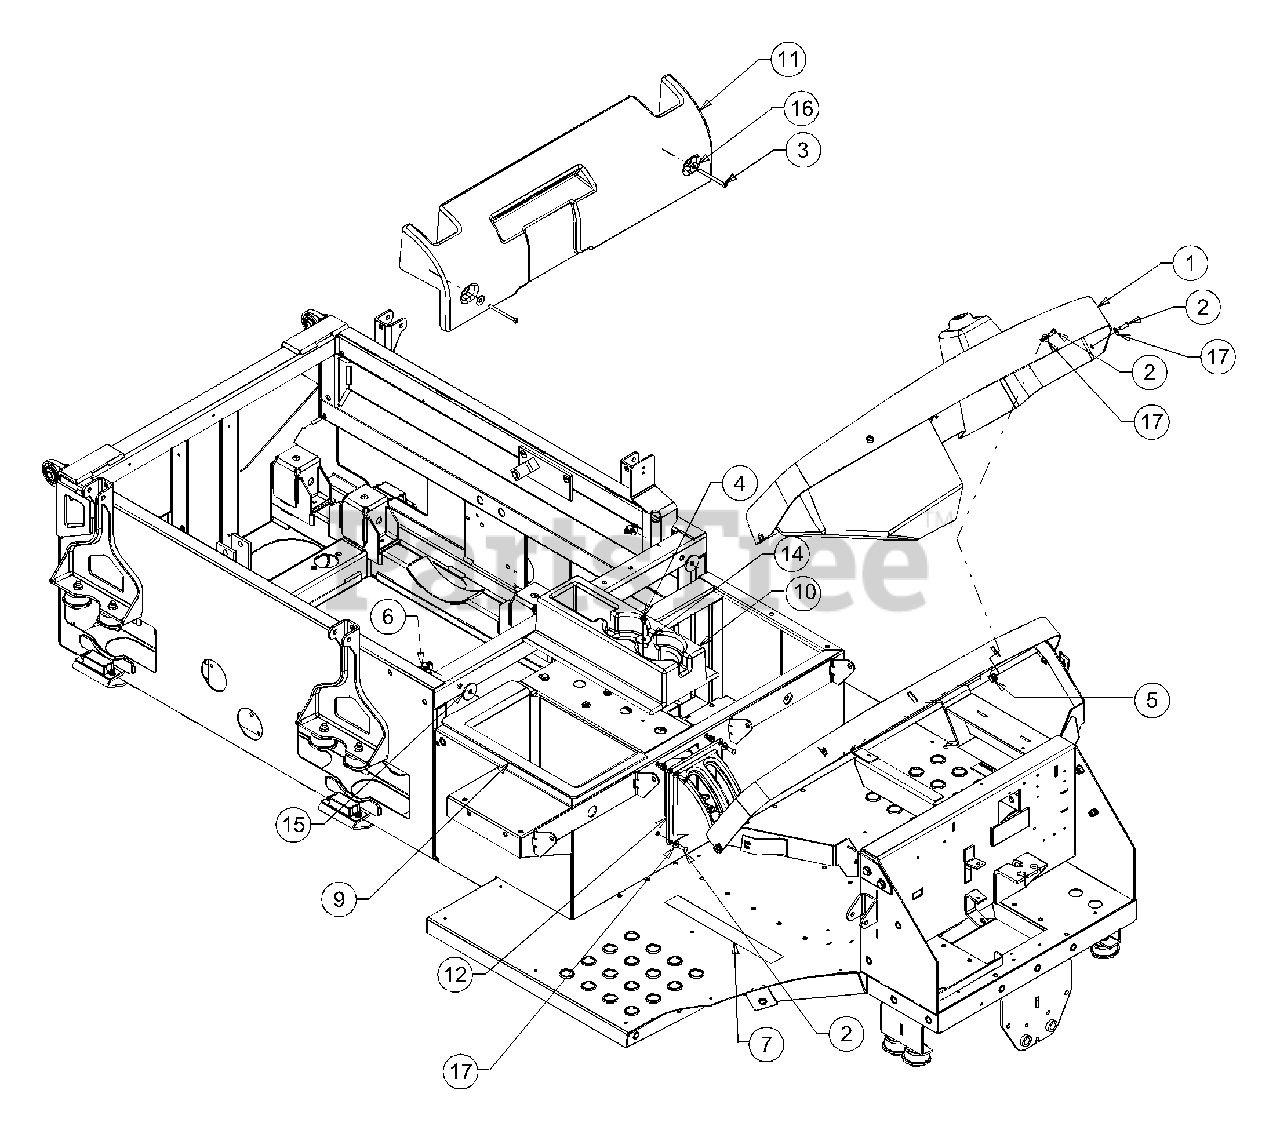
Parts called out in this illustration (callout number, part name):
1	Dash Assembly
2	Machine, Screw, 1/4-20 x .75
3	Screw, 1/4-20 x 3.0
4	Screw, Self-tapping, 1/4-20 x 0.500
5	Nut, Retainer, 1/4-20
6	Wing Nut, 1/4-20 (w/ Bell Washer)
7	Anti-Skid Strip
9	Tool Box
10	Console, Cup Holder
11	Panel, Airbox Cover
12	Panel, Shift Cover
14	Flat Washer, .350 x 1.25 x .06
15	Washer, Rubber, .375 x 1.5 x 1.25
16	Washer, Flat, .3125 x .875 x .04
17	Washer, Flat, .271 x .630 x .065
